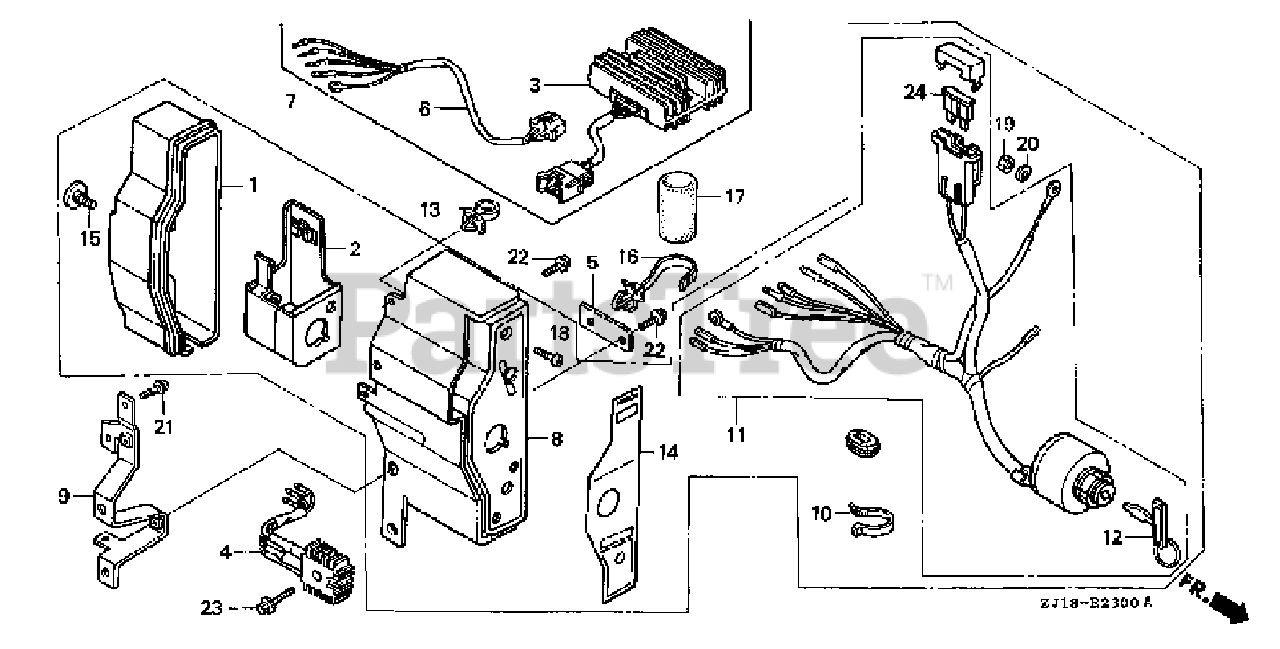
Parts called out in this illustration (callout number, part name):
1	CASE, CONTROL
2	BRACKET, CASE MOUNTING
4	RECTIFIER ASSY.
5	BRACKET, WIRE HARNESS CLIP
7	BOX ASSY., CONTROL
8	PANEL, CONTROL
9	STAY, CONTROL BOX
10	BAND
11	SWITCH ASSY., COMBINATION
12	KEY
13	HOLDER, STOP SWITCH WIRE
14	MARK, CONTROL BOX (EXTERNAL-REGULATOR)
15	SCREW, SPECIAL (6X12)
16	BAND, WIRE HARNESS (150MM) (BLUE)
17	TUBE, CORD (30MM)
18	SCREW, PAN (4X12)
19	NUT, HEX. (4MM) (NOT AVAILABLE)
20	WASHER, SPRING (4MM)
21	BOLT, FLANGE (6X10)
22	BOLT, FLANGE (6X12)
23	BOLT, FLANGE (6X32)
24	FUSE, BLADE (25A)
